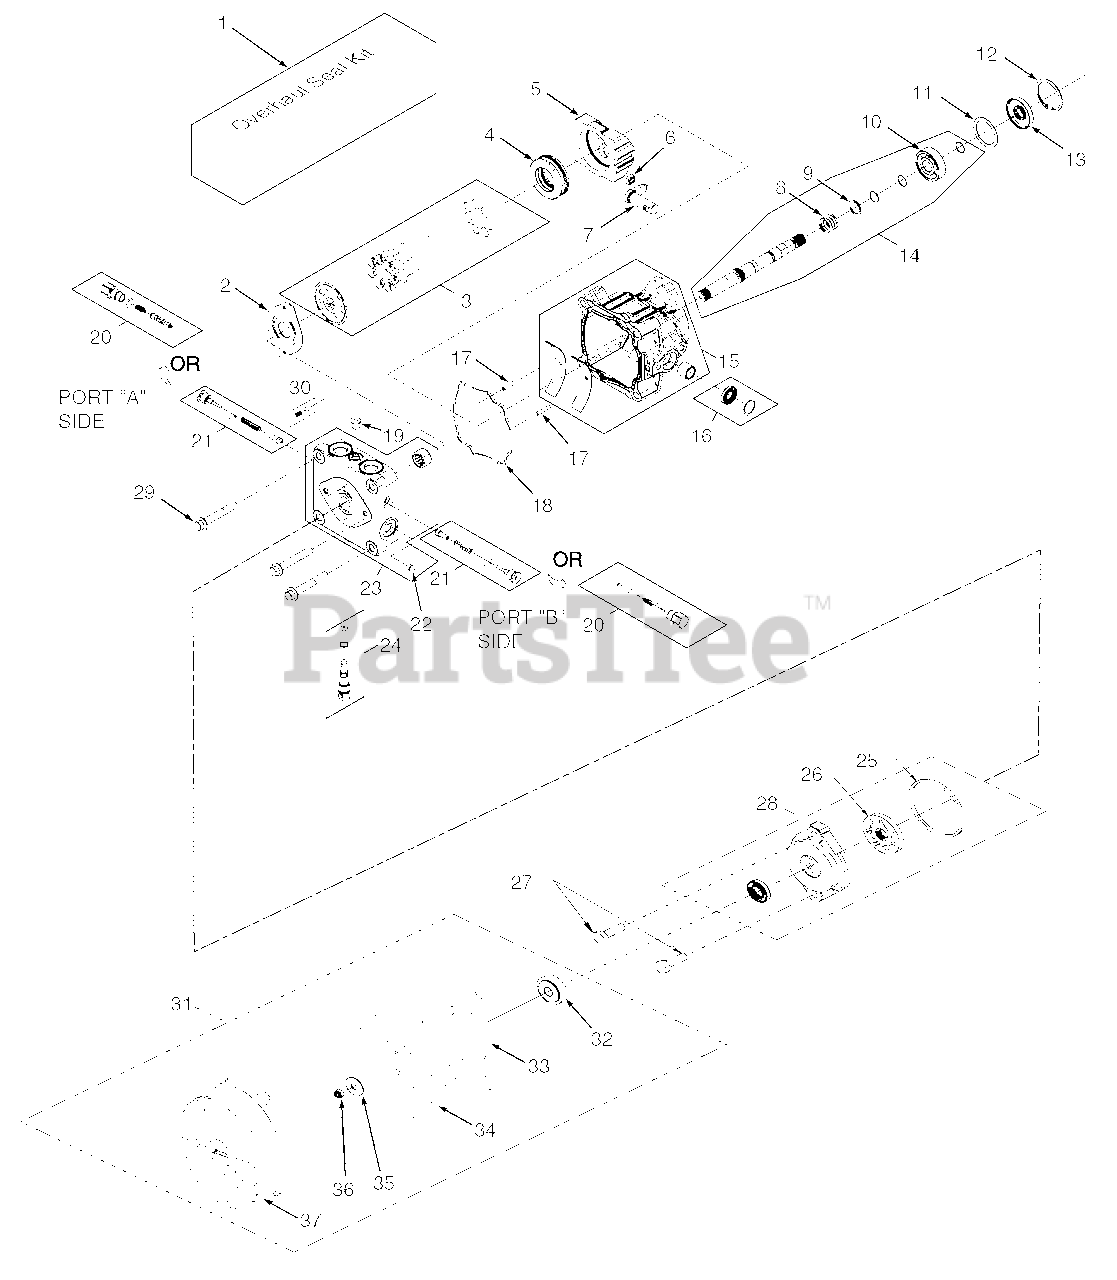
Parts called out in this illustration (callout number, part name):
1	Overhaul Seal Kit
2	Valve Plate
3	Cylinder Block Kit - 16cc
4	Thrust Ball Bearing Assembly
5	Variable Swashplate
6	Slot Guide
7	Trunnion Arm
8	Block Spring
9	Block Thrust Washer
10	Shaft Ball Bearing
12	Retaining Ring
14	Kit, Pump Shaft (keyed thru taper)
15	Housing Kit
16	Trunnion Seal Kit
18	O-Ring
19	Straight Thread Plug
20	Shock Valve Kit (.031 Orifice)
21	Shock Valve Kit (.024 Orifice)
22	Straight Thread Plug
23	End Cap Kit
24	Bypass Valve Kit
26	Gerotor Assembly (.19 cu.in./rev.)
27	Socket Head Cap Screw (M8 x 1.25-25mm)
28	Charge Pump Kit (.19 STD. Splined)
29	Hex Screw, Flanged Head (M10 x 1.50-65mm)
30	Charge Relief Kit
31	Fan Kit
33	Bracket, Shroud
35	Washer
37	Shroud
